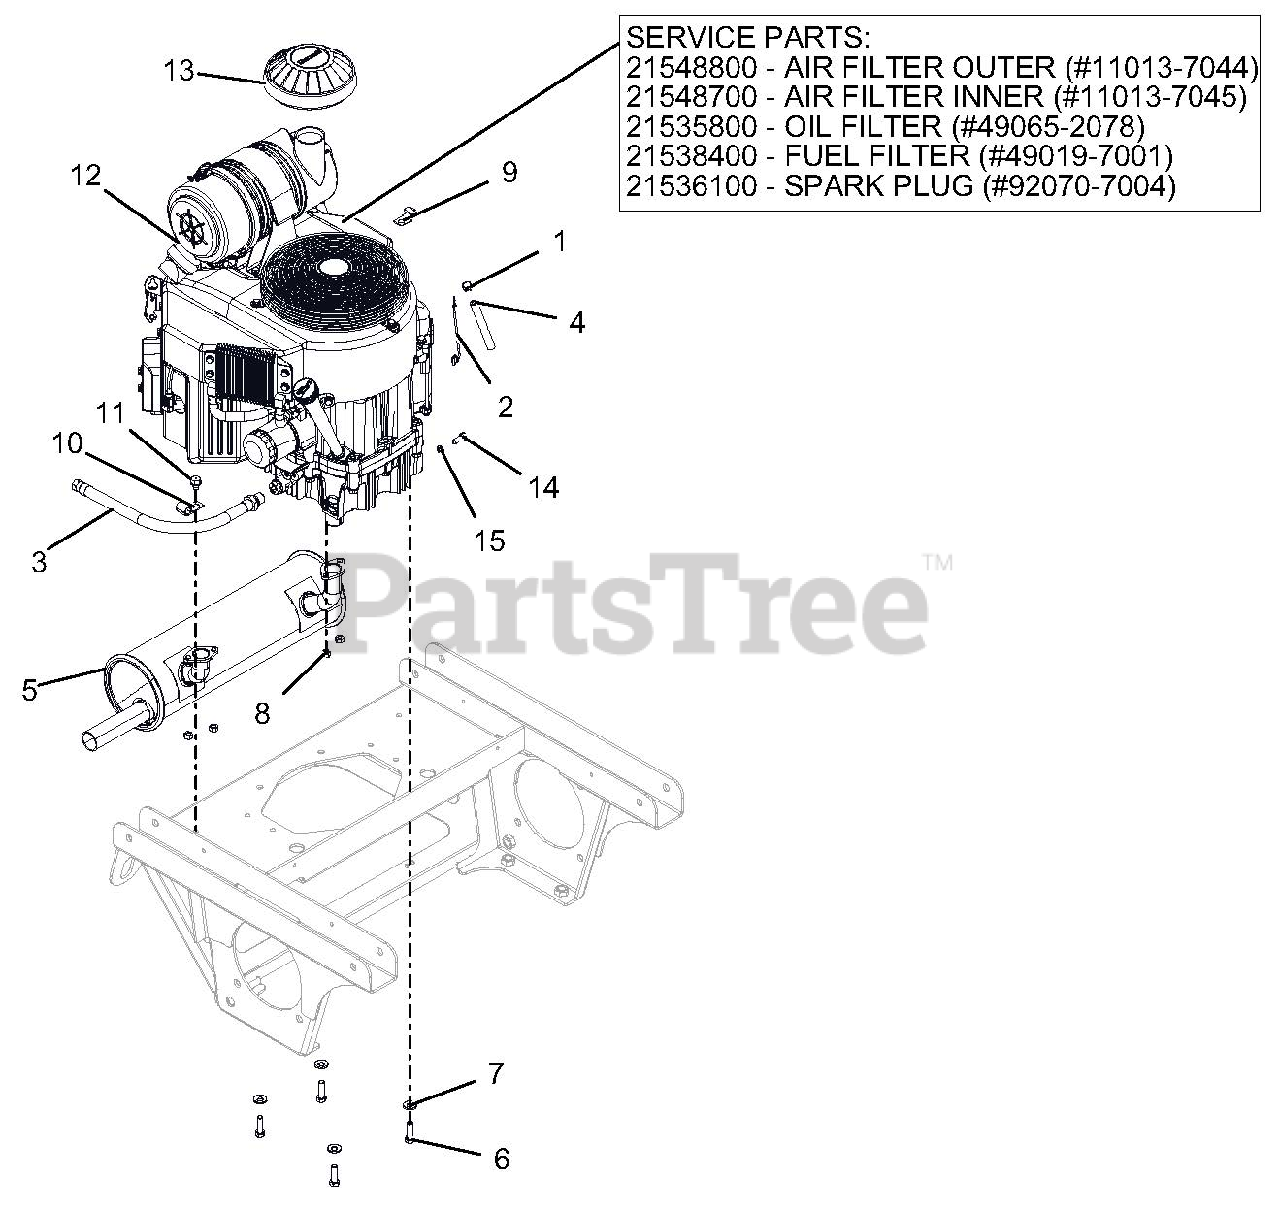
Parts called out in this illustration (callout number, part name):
1	CLAMP, FUEL LINE
2	LEAD - STARTER SOLENOID
3	HOSE, OIL DRAIN
4	.25 LOW-PERM GAS HOSE 18.00" LG - VALVE TO ENGINE
5	MUFFLER, 27-31 FX KAW
6	BLT-HEX .38-16X1.25 GR5 YWZC NYTORQ
7	WSHR, 3/8" SPRING DISC
8	NUT-LK-TOP M8-1.25 YWZC
9	CLAMP, J
11	SCR-TAP .38-16X.50 HWH TR YWZ
12	ENGINE, KAWASAKI FX850
12	AIR FILTER OUTER
12	AIR FILTER INNER
12	OIL FILTER
12	FUEL FILTER
12	SPARK PLUG
13	CAP, AIR CLEANER INTAKE
14	@BLT-HEX M8-1.25X20 YWZC
15	WSHR-LK .31X.078 REG YWZC
